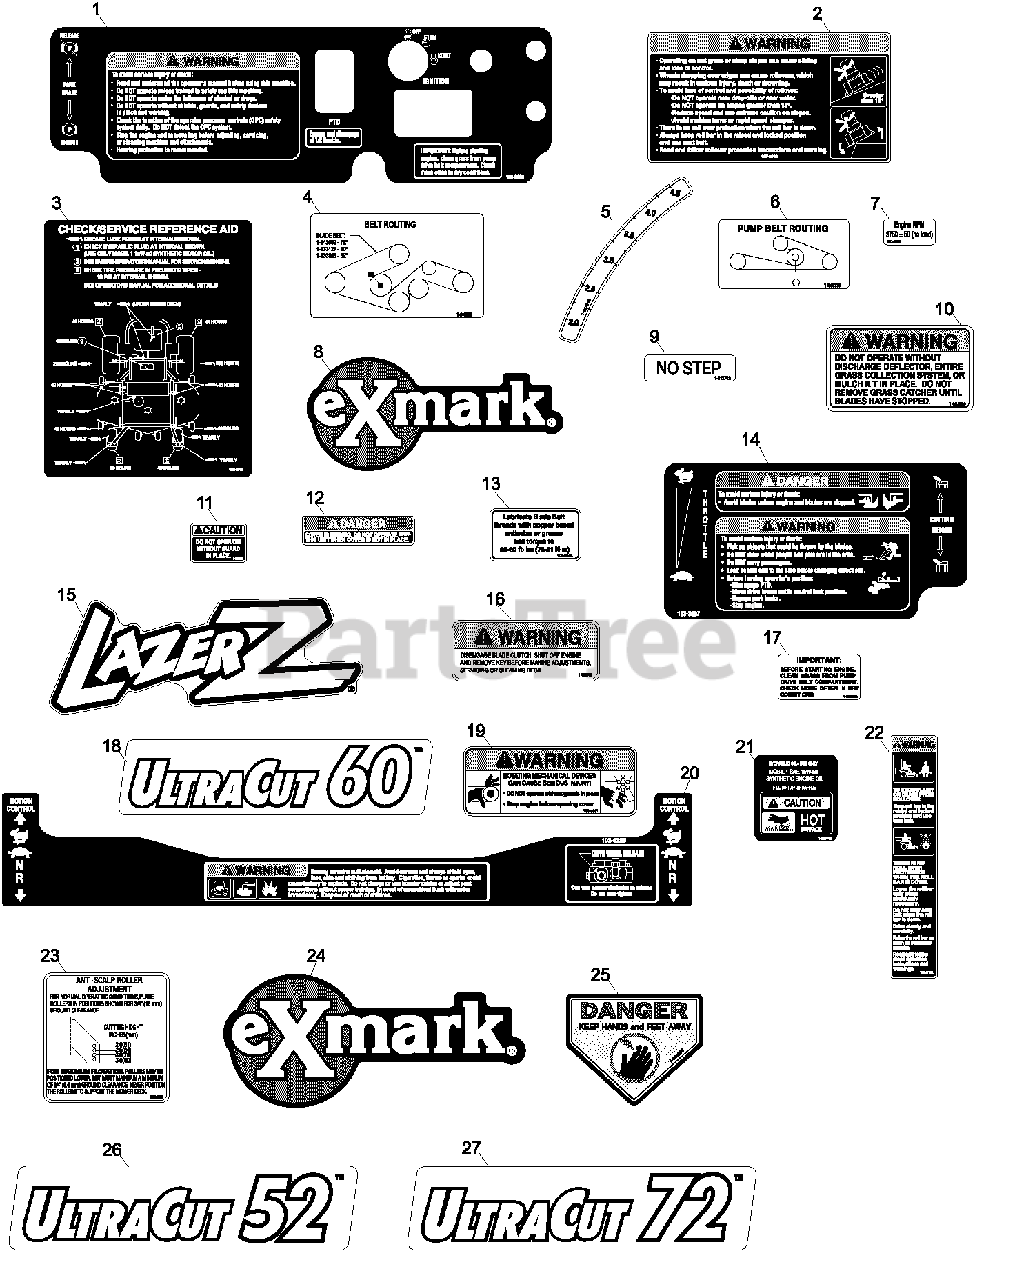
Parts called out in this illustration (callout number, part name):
1	DECAL, CONSOLE AS
2	DECAL-WARNING
3	DECAL,CHECK SERVICE LZ
4	DECAL,BELT ROUTING
5	DECAL-HEIGHT, DECK
6	DECAL-ROUTING, BELT
8	DECAL,EXMARK LOGO
9	DECAL,NO STEP
10	DECAL-WARNING, DISCHARGE
11	DECAL-GUARD
12	DECAL-COVER, MISSING
13	DECAL,BOLT TORQUE
14	DECAL, CONSOLE THROTTLE A
15	DECAL,LAZER MODEL
16	DECAL,WARNING
17	DECAL-IMPORTANT
18	DECAL,ULTRACUT 60
19	DECAL-DEVICES, ROTATING
22	DECAL-WARNING, FOLDING RO
23	DECAL,ANTISCALP
24	DECAL,EXMARK LOGO
25	DECAL-DANGER
26	DECAL,ULTRACUT 52
27	DECAL,ULTRACUT 72
